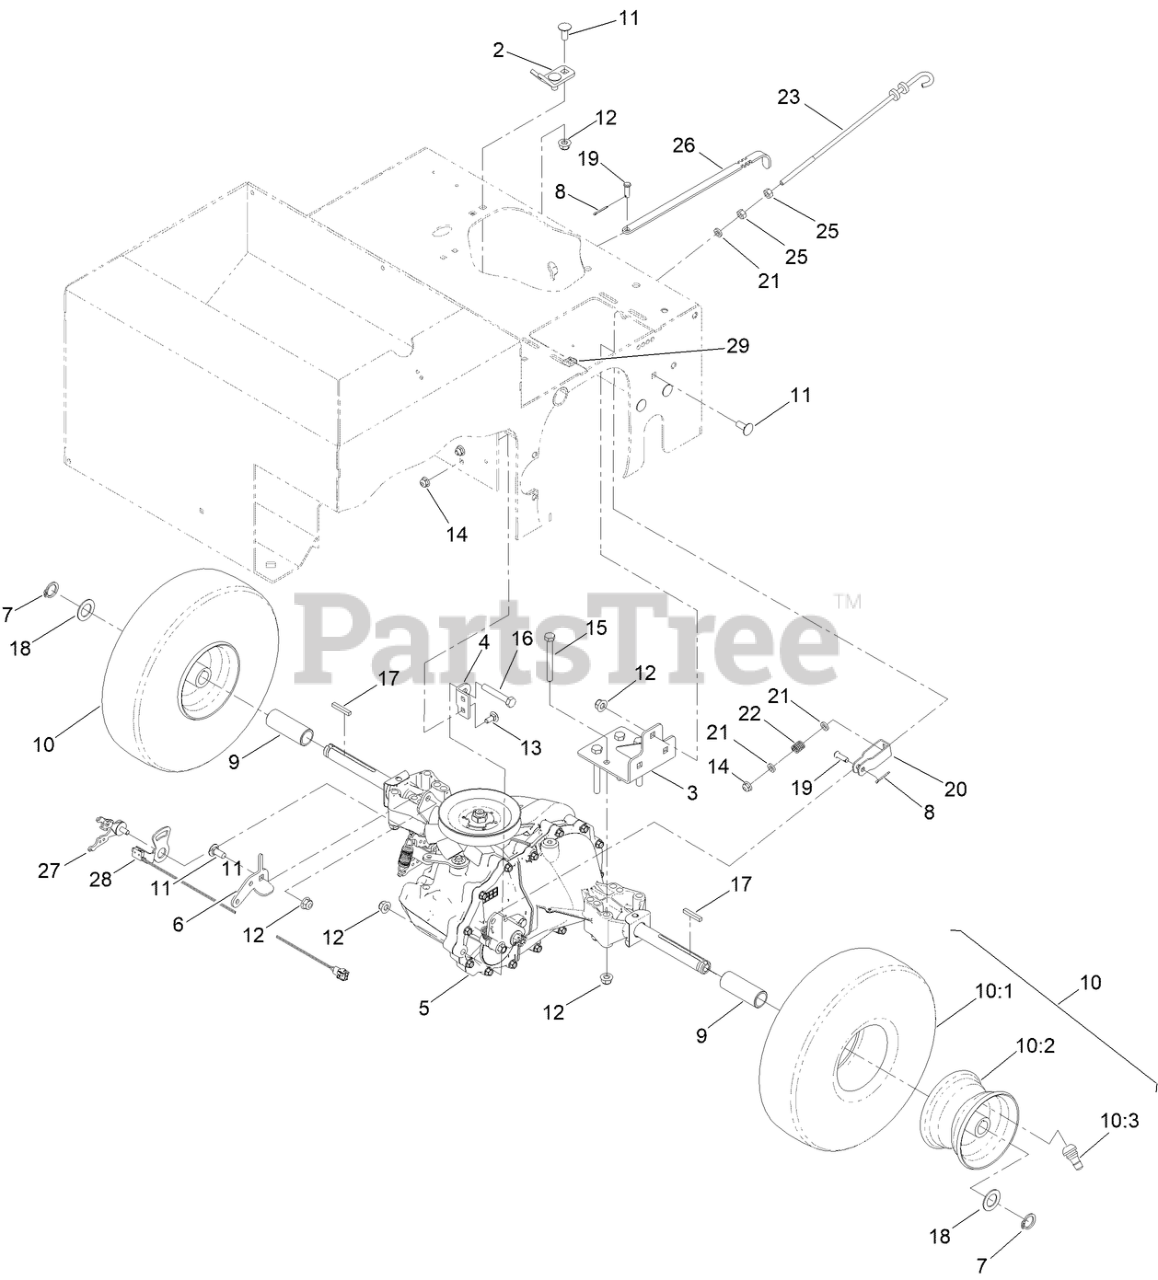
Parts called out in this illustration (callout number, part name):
2	BRACKET-CABLE
3	BRACKET-AXLE
4	BRACKET-TRANSAXLE, TORQUE
5	TRANSAXLE ASM
6	BRACKET-TRANSAXLE
7	RING-RETAINING
8	PIN-COTTER
9	SPACER
10	WHEEL ASM
10:2	WHEEL-RIM
10:3	VALVE
11	SCREW-CARR
12	NUT-HF, NI
13	SCREW-CARR
14	NUT-HF
15	SCREW-HH
16	SCREW-HH
17	KEY-SQUARE
18	WASHER
19	PIN-CLEVIS
20	CLEVIS
21	SPACER-PLATE, PIVOT
22	SPRING-COMPRESSION
23	ROD-BRAKE
25	NUT-HEX
26	LEVER-BYPASS
27	KIT-HYDRO RTN BI DIR ARMS
28	SWITCH-HYDRO REVERSE
29	CLIP-EDGE
